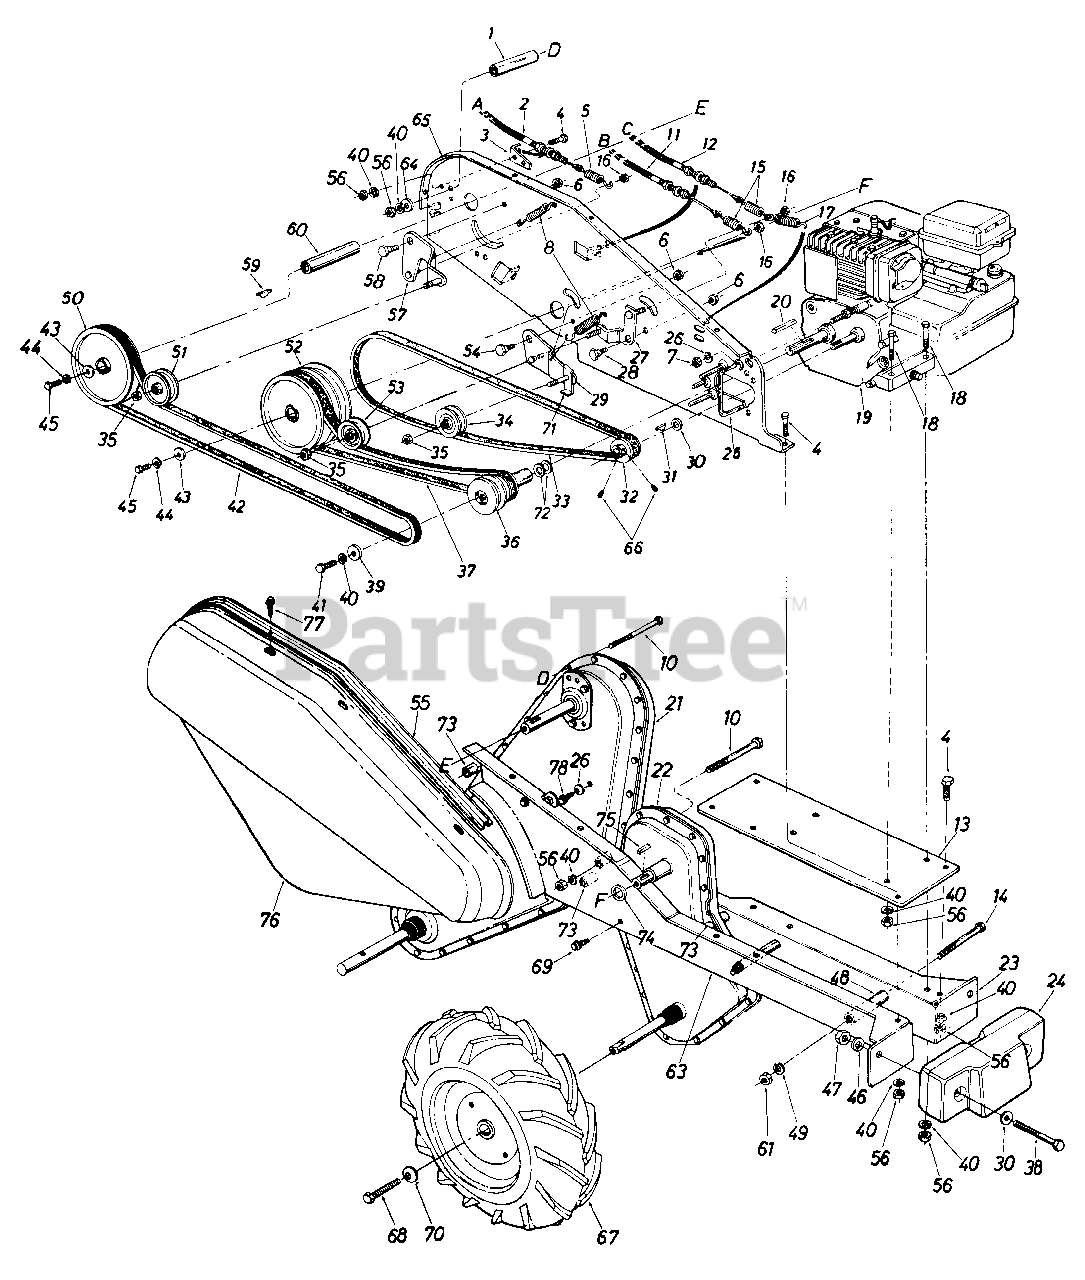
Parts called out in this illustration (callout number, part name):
1	Spacer .375" I.D. x .5" O.D. x 2" Lg.
2	Clutch Control Cable
3	Clutch Cable Bracket
4	Hex Bolt 5/16-18 x .75" Lg.
5	Extension Spring .50" O.D. x 2.5" Lg.
6	Hex Cent. L-Nut 3/8-16 Thd.
7	Hex Nut 1/4-20 Thd.
8	Extension Spring .50" O.D. x 1.55" Lg.
10	Hex Bolt 5/16-18 x 3" Lg.
11	Clutch Control Cable 42" Lg.
12	Clutch Control Cable 41" Lg.
15	Springs
16	Hex Cent. L-Nut 1/4-20 Thd.
17	Extension Spring .41" O.D. x 2.05" Lg.
18	Hex Bolt 5/16-18 x 1.5" Lg.
19	Engine
20	Sq. Key 3/16 x 1.00" Lg.
21	Chain Case Comp.-Tines
22	Chain Case Comp.-Wheels
25	Belt Keeper
26	Bell-Wash. .265" I.D. x .75" O.D.
29	Idler Brkt. Ass'y.
30	Fl-Wash. .51" I.D. x 1.0"
31	#5 Hi-Pro-Key 1/8" x 5/8" Dia.
32	1/2" V-Pulley 2.25" O.D. x .503" I.D.
33	"V"-Belt
34	"V"-Belt Idler 2.62" O.D.
35	Hex Ins. L-Nut 3/8-24 Thd.
36	1/2" "V"-Pulley Ass'y.
37	"V"-Belt
38	Hex Bolt 1/2-13 x 4" Lg.
39	Fl-Wash. .344" I.D. x 1.125"
40	L-Wash. 5/16" I.D.*
41	Hex Bolt 5/16-24 x 1.00" Lg.
42	"V"-Belt
43	Fl-Wash. 1/4" I.D. x .93" O.D.
44	L-Wash. 1/4" I.D.
45	Hex Bolt 1/4-28 x .75" Lg.
46	L-Wash. 1/2" I.D.
47	Hex Nut 1/2-13 Thd.
48	Spacer .38" I.D. x .62" O.D. x 2.18" Lg.
49	L-Wash. 3/8" I.D.
50	Fl-Pulley w/Flanges 5" O.D.
51	Fl-Idler w/Flanges 3.75" O.D.
52	Double Fl-Pulley 5/8" I.D.
53	Fl-Idler w/Flanges 2.12" O.D.
54	Shld. Bolt .500" Dia. x .170" Lg.
55	Flange Extension
56	Hex Nut 5/16-18 Thd.
59	#61 Hi-Pro-Key 3/16" x 5/8" Dia.
60	Spacer .647" I.D. x 2 75" Lg.
61	Hex Nut 3/8-24 Thd.
65	Side Plate Ass'y.
66	Set Scr. 1/4-28 x 25" Lg.
67	R.H. Wheel Ass'y. Comp. 13 x 5
68	Hex Bolt 5/16-24 x .62n Lg.
69	Hex Self-Tap Scr. 5/16-24 x .5" Lg.
70	Bell-Wash. 5/16" I.D.
71	Belt Keeper Brkt.
72	Fl-Wash. 75" I.D. x 1.5"
73	Spacer .326" I.D. x .47" O.D. x .96" Lg.
74	Fl-Wash. .635" I.D. x 1" O.D.
75	Sq. Key 3/16 x .75' Lg.
78	Hex Wash. S-Tap Scr. 1/4-20 x .38" Lg.
